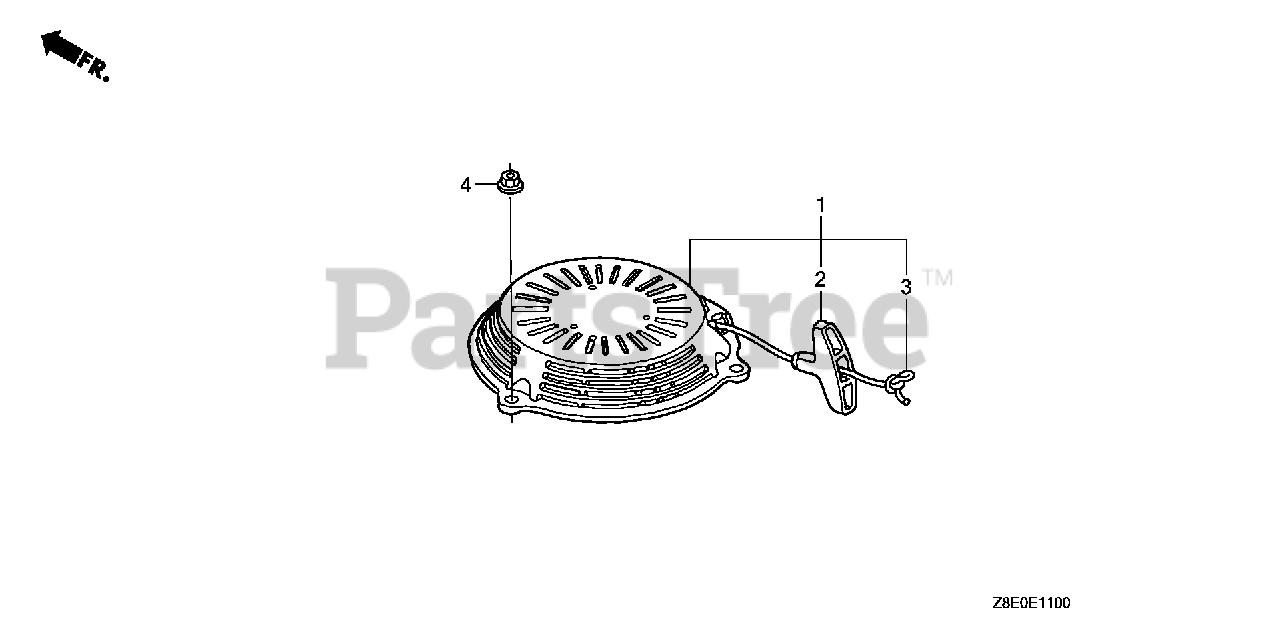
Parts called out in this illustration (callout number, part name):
1	STARTER ASSY., RECOIL *R280* (POWER RED)
1	STARTER ASSY., RECOIL *R280* (LONG ROPE) (POWER RED)
2	KNOB, RECOIL STARTER
3	ROPE, RECOIL STARTER (LONG TYPE)
3	ROPE, RECOIL STARTER (Honda Code 5580642). (#3.5X90")
4	NUT, FLANGE (6MM)
